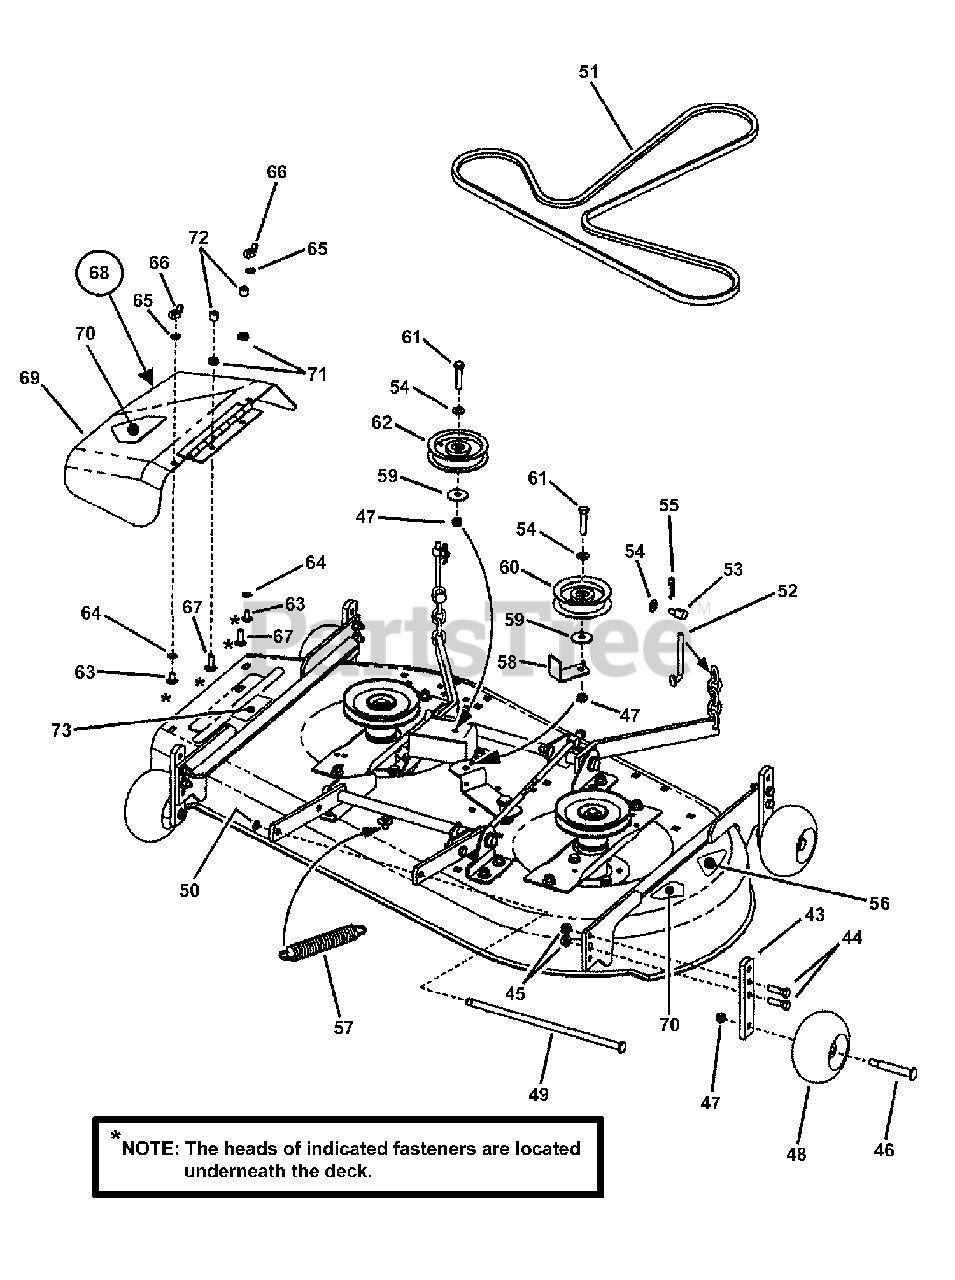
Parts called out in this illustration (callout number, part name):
43	POST, Anti Scalp 42" Deck
44	SCREW, 3/8-16 x 1-1/4", Hex Head Cap, GR 5
45	NUT, 3/8-16 Hex Flange Lock
46	BOLT, Gage Wheel, 3/8-16 x 3-3/8" Hex Head Shoulder
47	NUT, 3/8-16 Hex Center Lock, GR 5 or B
48	WHEEL, Gage
49	ROD, Deck Support
50	RING, .438 External Retaining
51	BELT, HA Sect., 94.5" nom. effective length
52	ADJUSTER, Chain (5/16-18 thread)
53	SWIVEL, Adjustment
54	WASHER, 3/8" SAE Flat
55	HAIR PIN, 3/32 x 1-1/2"
56	DECAL, 42" Deck
57	SPRING, Extension 1.03 Dia. X 6.8" long
58	BELT GUIDE, 38/42 Idler, HOZ
59	WASHER, .406 I. D. Cone
60	IDLER, Flat (4.00 O.D.)
61	SCREW, 3/8-16 x 1-3/4" Hex Head Cap, GR 5
62	IDLER, 4.12" Outside Diameter, Flat
63	BOLT, 5/16-18 x 5/8" Short Neck Carriage, GR 5
64	RETAINER, 5/16" Bolt
65	WASHER, .32 x .58 x .08 Split Lock
66	WING LOCKNUT, 5/16-18
67	BOLT, 5/16-18 x 1" Short Neck Carriage, GR 5
68	ASSEMBLY, Chute & Decal
69	WELDMENT, Side Chute
70	DECAL, Danger, Cut Finger
71	NUT, 5/16-18 Hex Flange Lock, GR 5
72	VINYL CAP, 1/4" I.D.
73	DECAL, Chute/Deflector
